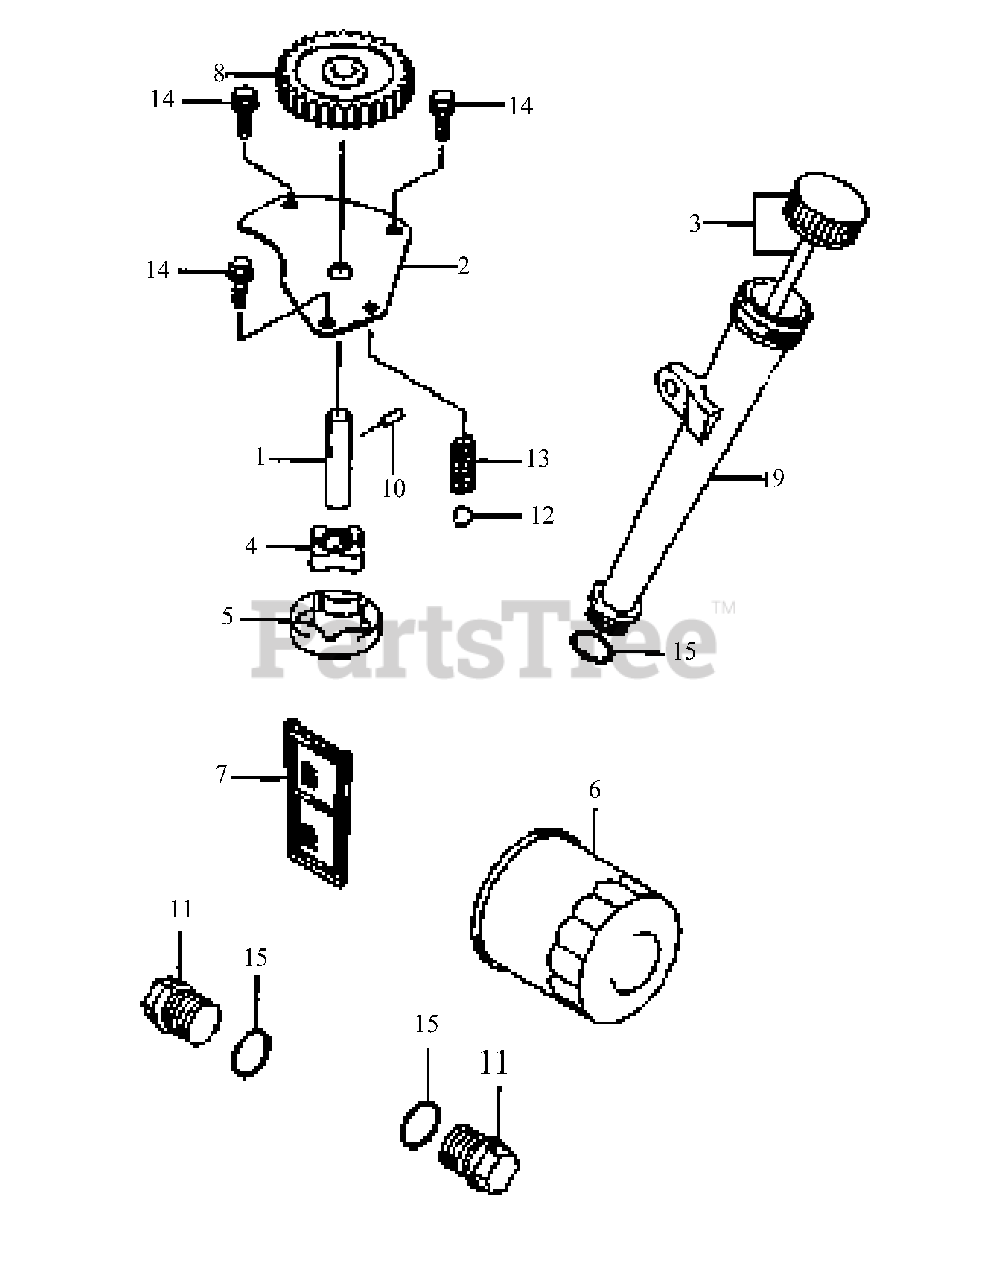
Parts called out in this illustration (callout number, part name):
1	Shaft, Oil Pump
4	Rotor-Pump In
5	Rotor-Pump Out
6	Filter-Oil
7	Filter-Oil Screen
8	Gear-Spur
10	Pin
11	Plug
